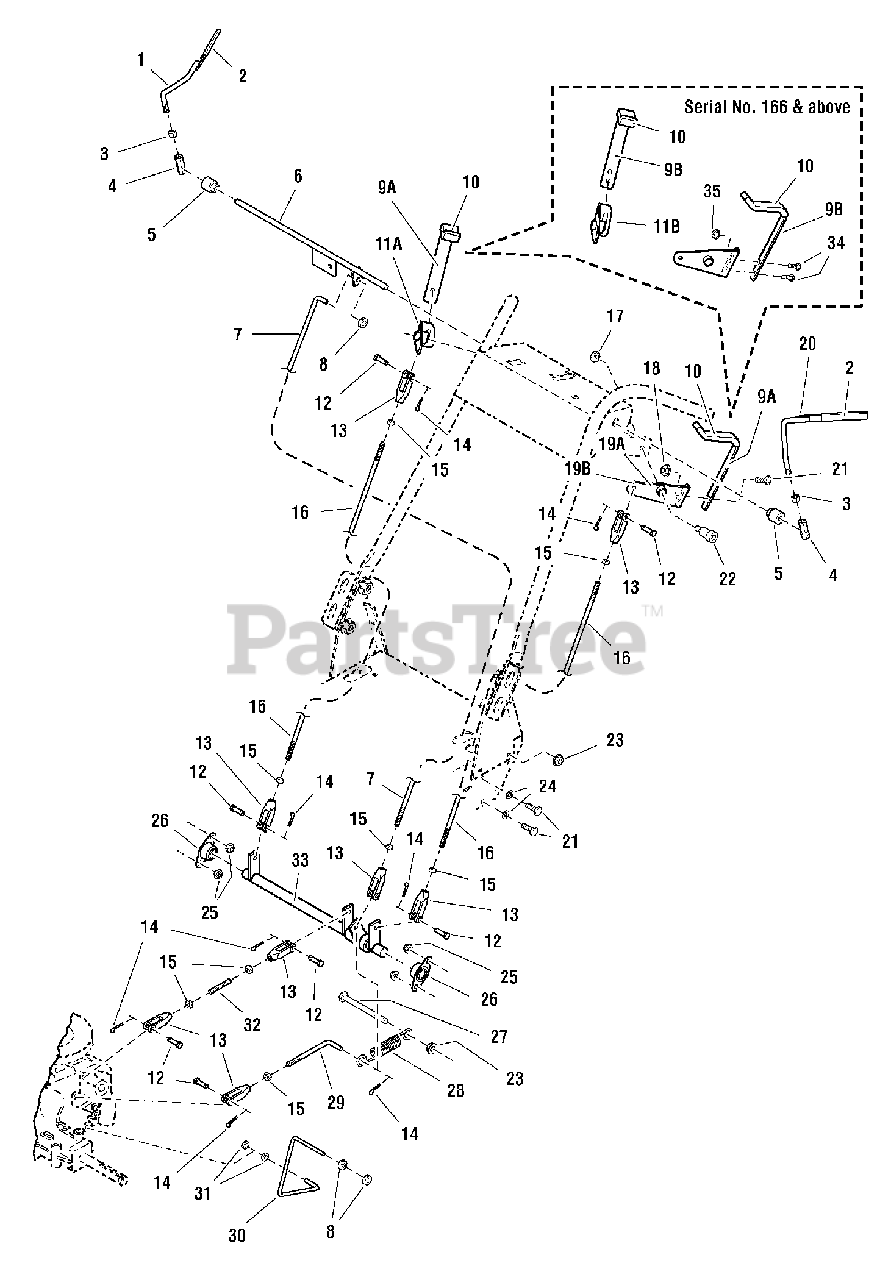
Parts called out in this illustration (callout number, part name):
1	OPERATOR PRESENCE HANDLE - RH, Complete (includes Ref 2)
3	NUT, Hex, 3/8-16
4	ADJUSTER LINKAGE
5	SHOULDER SPACER
8	COLLAR, Set, 5/16
9A	THUMB CONTROL LEVER, Complete (includes Ref No. 10) (S/N: 101-165)
9B	THUMB CONTROL LEVER, Complete (includes Ref No. 10) (S/N: 166 & up)
11A	PIVOT CONTROL - RH (S/N: 101-165)
11B	PIVOT CONTROL - RH (S/N: 165 & up)
12	PIN, Clevis, 5/16 x 1
13	CLEVIS, Plastic, 5/16-24
14	PIN, Cotter
15	NUT, Hex, 5/16-24
16	THUMB CONTROL ROD
17	NUT, Hex, Side Lock, 3/8-16
18	NUT, Hex Serrated Flange, 5/16-18
19A	PIVOT CONTROL - LH (S/N: 101-165)
19B	PIVOT CONTROL - LH (S/N: 166 & up)
20	OPERATOR PRESENCE HANDLE - LH, Complete (includes Ref 2)
21	CAPSCREW, Hex Head, 5/16-18 x 3/4
22	SHOULDER BOLT, 1/2 x 1
23	NUT, Hex Serrated Flange, 3/8-16
24	WASHER, 5/16
25	NUT, Hex Nylon Lock, 5/16-18
26	BEARING, Flange
27	CAPSCREW, Hex Head, 3/8-16 x 4
28	SPRING, Extension
29	BRAKE LINKAGE ROD
30	DUMP VALVE ROD
31	COLLAR, Set, 1/4
33	CONTROL SHAFT ASSEMBLY
34	CAPSCREW, Hex Head, 1/4-20 x 3/4
35	NUT, Hex Serrated Flange, 1/4-20
